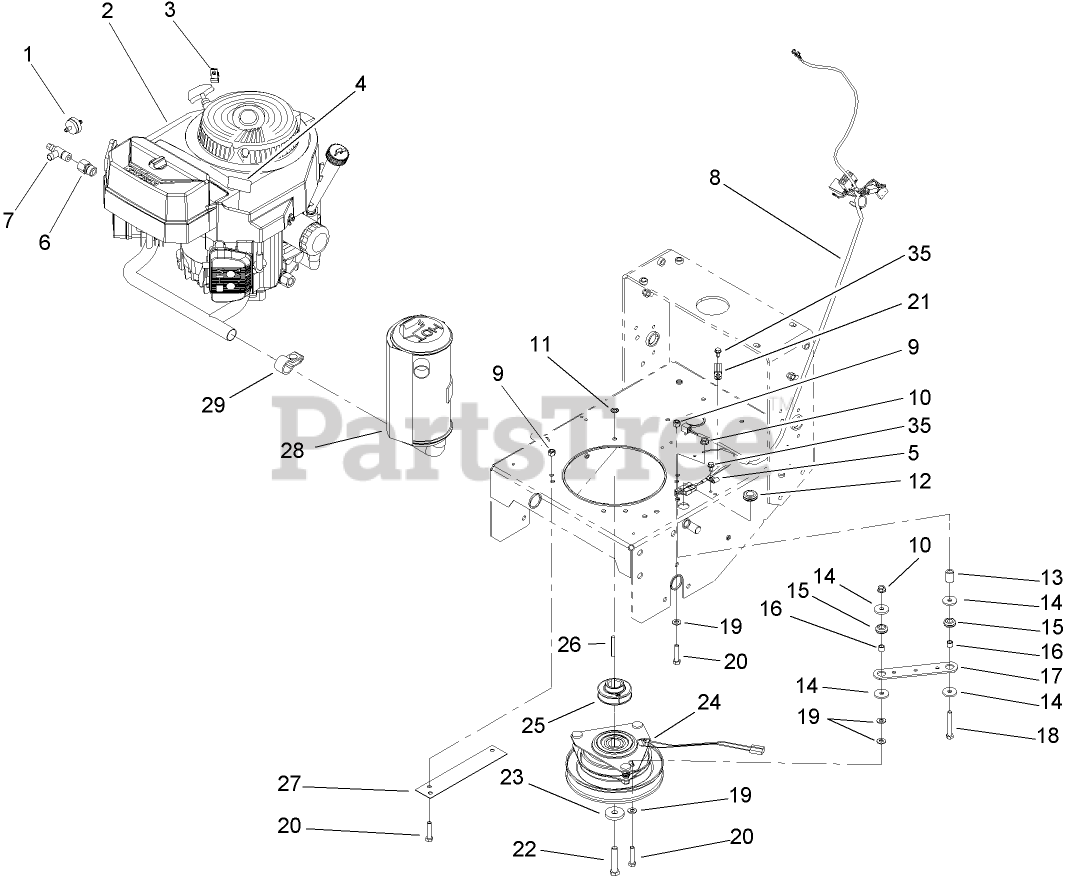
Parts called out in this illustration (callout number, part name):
1	FILTER-FUEL
3	CLAMP-CABLE
4	DECAL-WARNING
5	CLIP-CLOSED, INSULATED
6	Adapter
7	Valve-Drain, Oil
8	HARNESS-WIRE
9	NUT-LOCK, NI
10	NUT-HF
11	WASHER-LOCK
12	GROMMET
13	TUBE-RETAINER
14	WASHER
15	GROMMET
16	SPACER
17	STRAP-CLUTCH, BRAKE
18	SCREW-HH
19	WASHER-PLAIN
20	SCREW-HH
21	CLAMP-R
22	SCREW-HH
23	WASHER
24	CLUTCH / BRAKE ASM
25	PULLEY-DRIVE
26	KEY-SQUARE
27	COVER-PULLEY
28	MUFFLER
29	CLAMP-MUFFLER
35	SCREW
